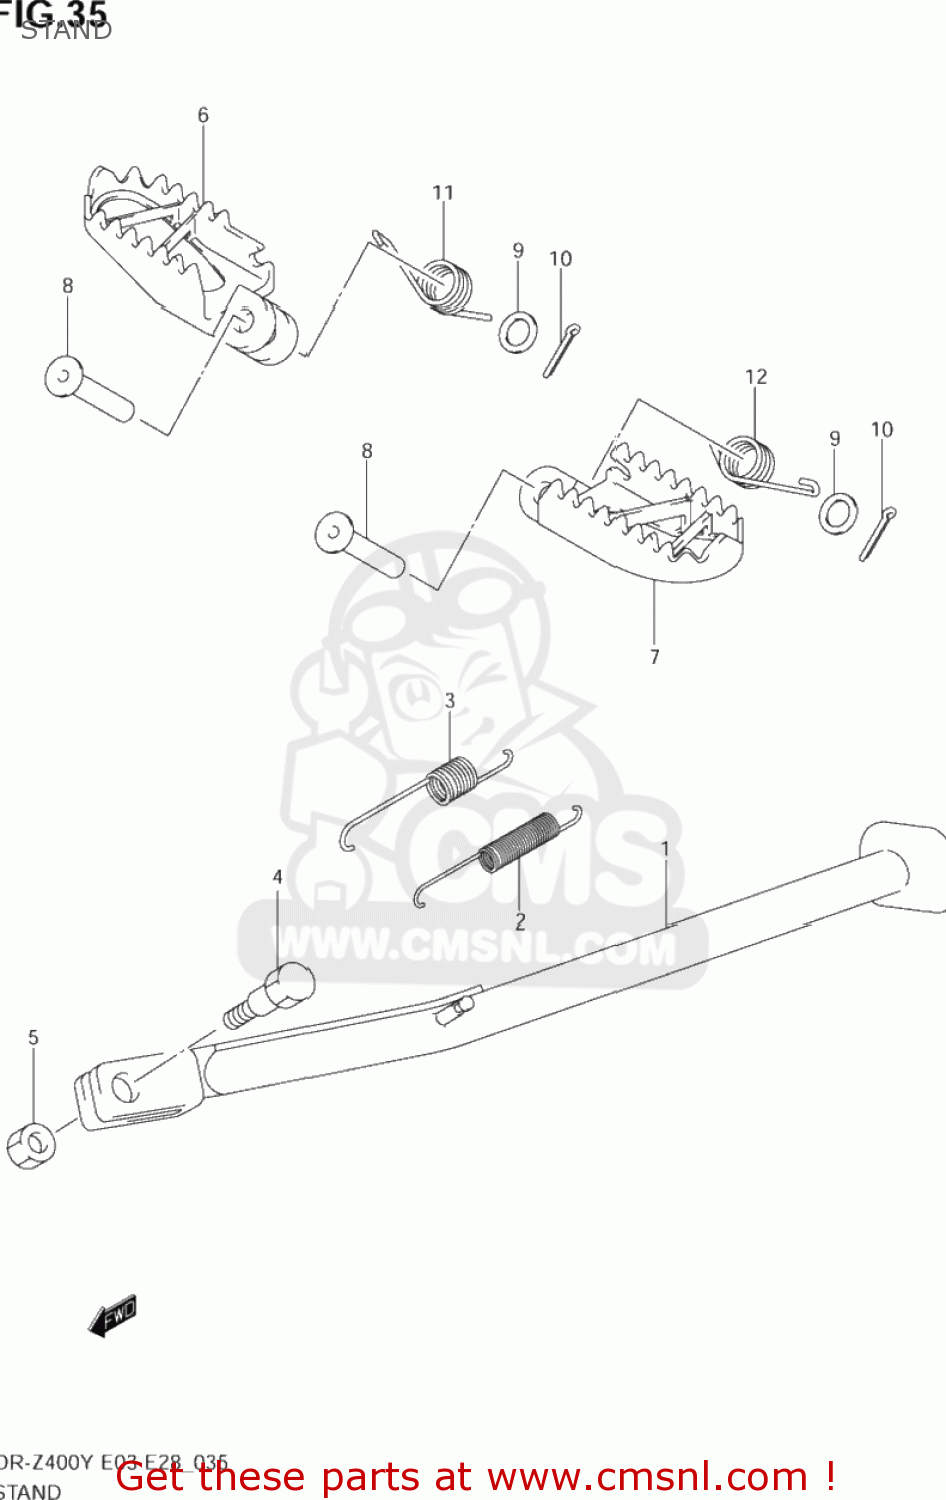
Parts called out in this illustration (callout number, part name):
1	STAND,PROP
2	SPRING
3	SPRING
4	BOLT(10X33)
5	NUT,PROP STAND
6	FOOTREST,R
7	FOOTREST,L
8	PIN(10X41.5)
9	WASHER
10	PIN 25X20
11	SPRING
12	SPRING
